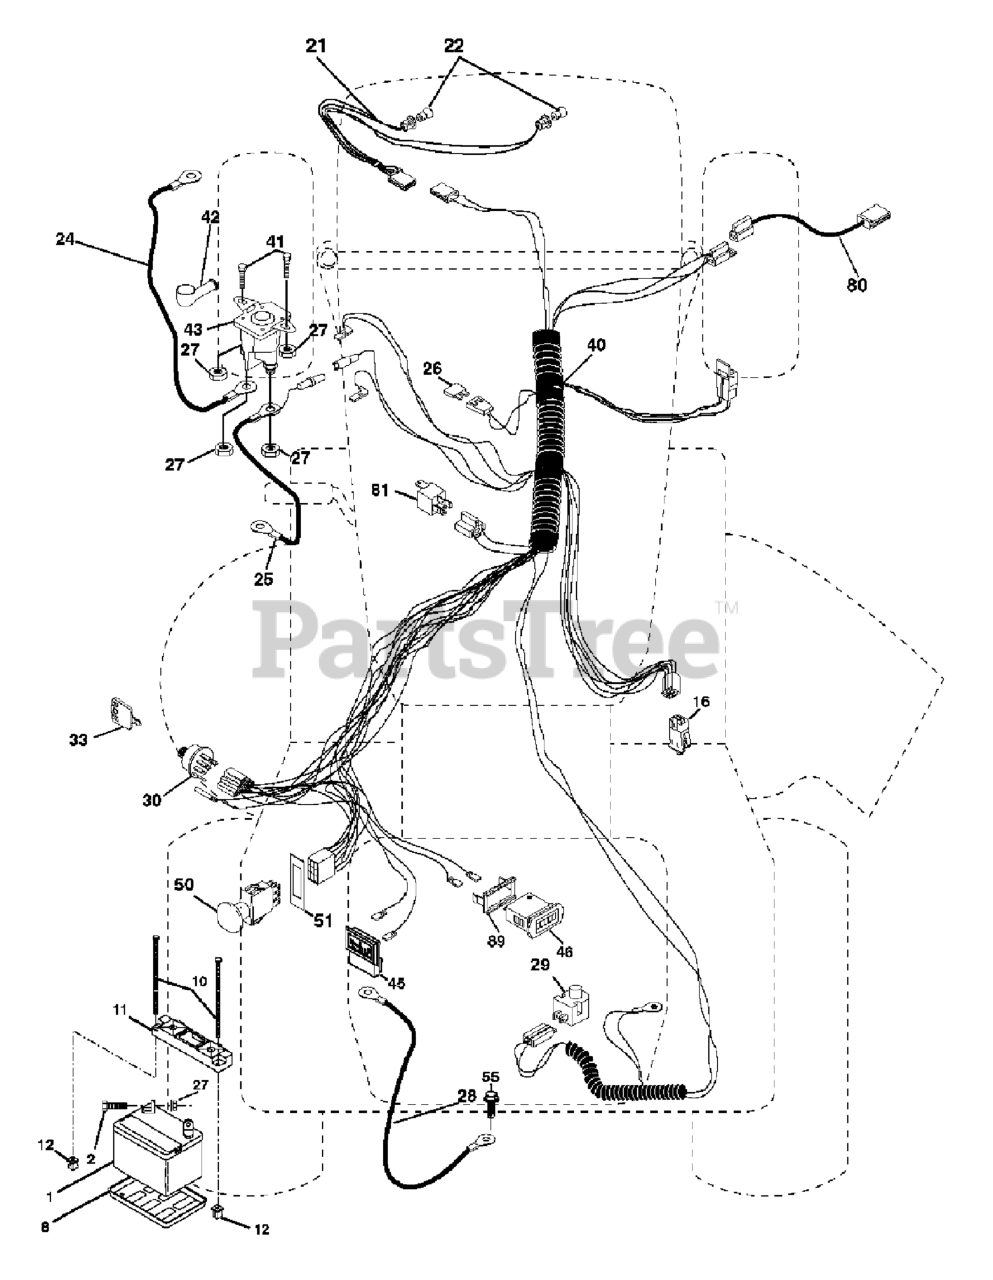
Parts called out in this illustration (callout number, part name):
1	BATTERY 12V .35 AMP
2	BOLT.HEX.1/4.X.3/4.DICHROMATE
8	BATTERY TRAY T
10	BOLT 1/4-20 X 7.5
11	BATTERY HOLDDOWN FRONT MOUNT
12	NUT, PUSH NYLON 1/4" BATTERY
16	SWITCH INTERLOOK PUSH-IN
21	HARNESS.W/LIGHT SOCKET
24	CABLE BATTERY 6 GA 22" W/16W
25	BATTERY CABLE GT
26	FUSE 20AMP
27	NUT
28	CABLE GROUND 6 GA 21" 90T BLK
29	PLUNGER SWITCH (COLOR:OLIVE)
30	IGNITION SWITCH
33	KEY MLD GEN DELTA
40	HARNESS IGN.
41	BOLT
42	TERMINAL COVER
43	SOLENOID
46	HOUR METER
50	RP.PTO.SWITCH.8 TERMINAL.BLACK
51	FRAME RETAINING RING
55	Screw Thdrol 5/16-18 x 1-1/2 Tyt
80	HARNESS, CLUTCH
81	RELAY.ASSY.T
89	BRACKET SNAP-IN HOURMETER
